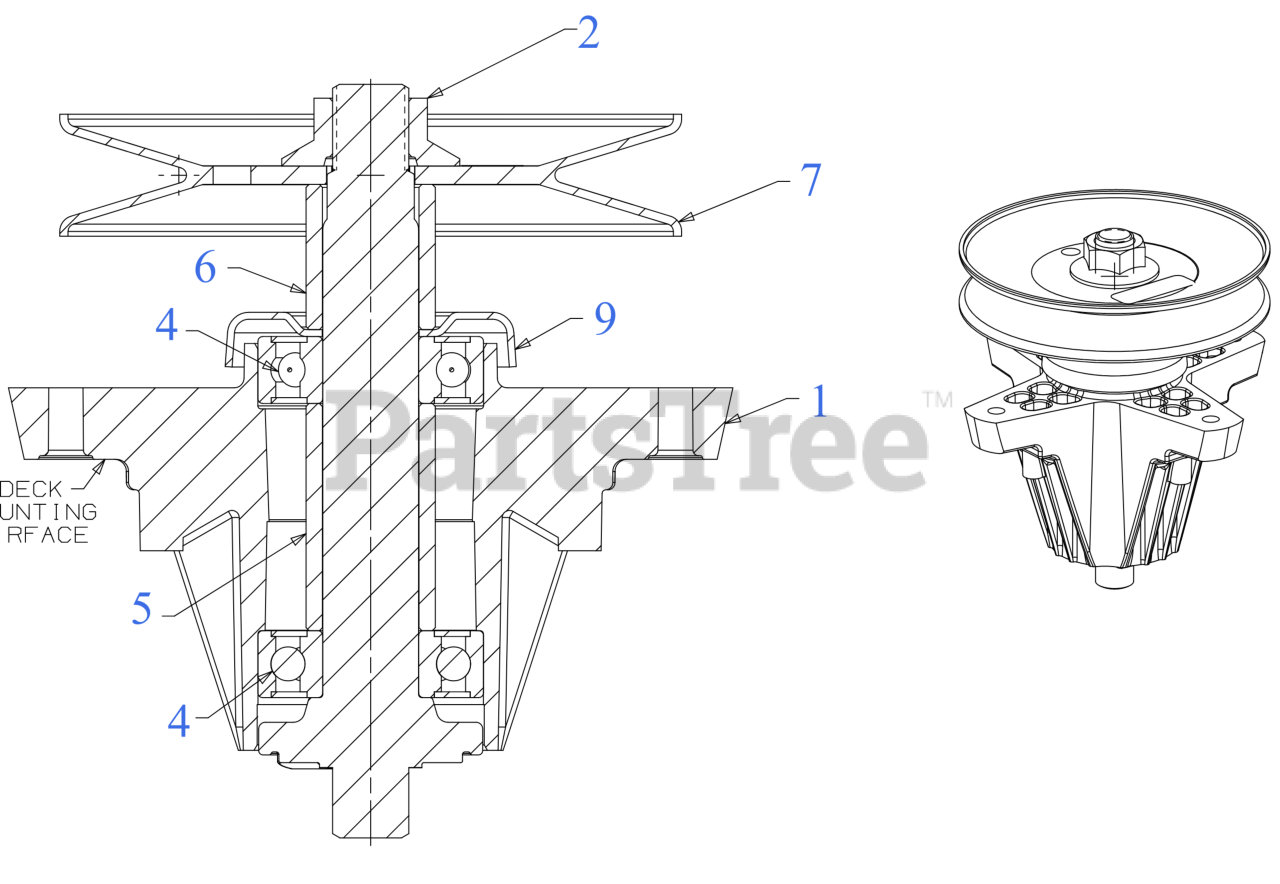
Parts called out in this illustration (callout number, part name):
1	DECK SPINDLE HOUSING
2	FLANGE NUT 5/8-18
4	BALL BEARING
5	SPACER- .792 x 1.060 x 1.860
6	SPACER .792 x 1.060 x 1.191
7	SPINDLE PULLEY 5.2 DIA
9	SHIELD-BRG DECK
